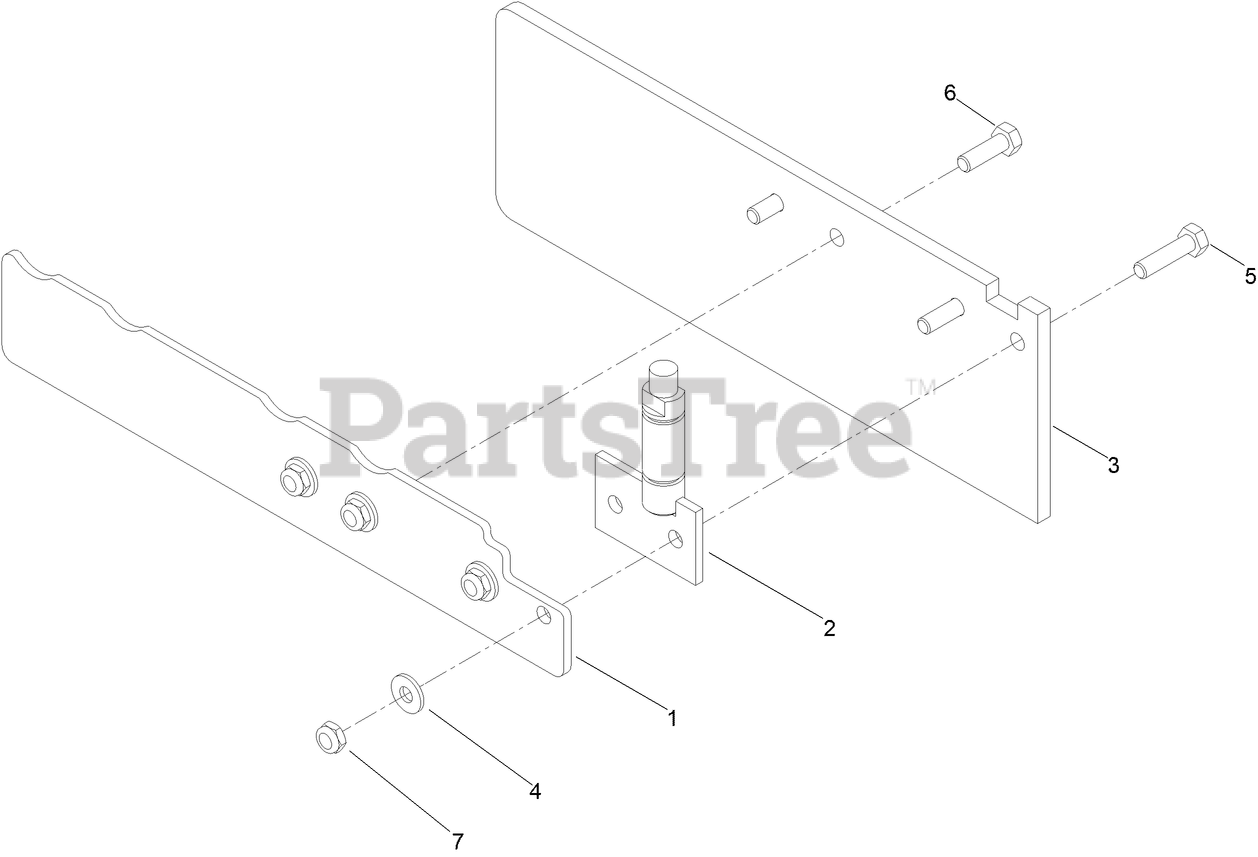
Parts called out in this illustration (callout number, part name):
1	PLATE-DOOR
2	HINGE-GATE
3	GATE-CHUTE, RUBBER
4	WASHER-FLAT
5	SCREW-HH
6	SCREW-HH
7	NUT-LOCK, NI
